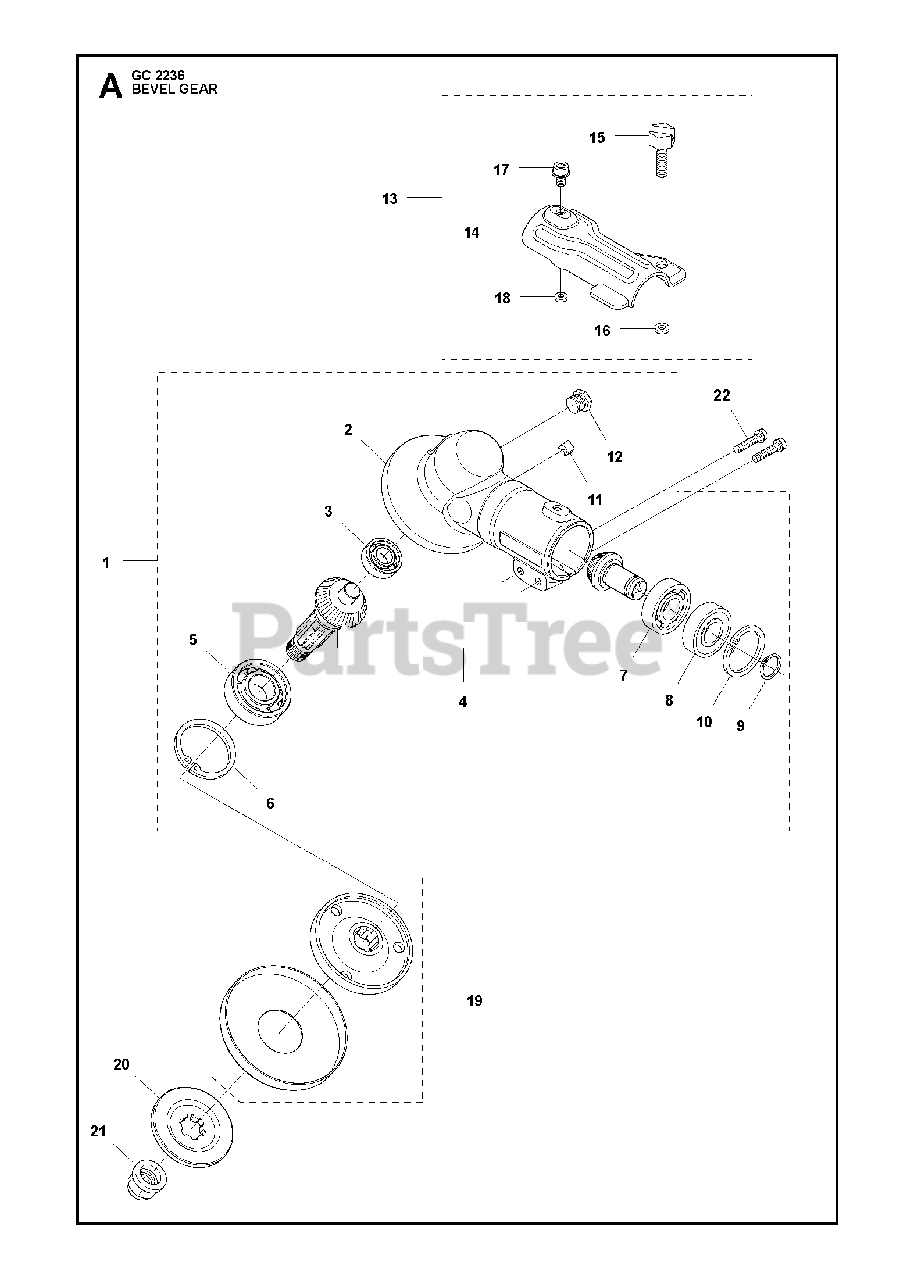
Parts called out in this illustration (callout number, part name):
1	%GEAR CASE ASSY
2	GEAR CASE
3	BALL BEARING 24X9X1/609ZR
4	SPARE PARTS KIT
5	BALL BEARING
6	RETAINING RING
7	BALL BEARING
8	BALL BEARING
9	SEEGER CLIP
10	RETAINING RING SGH 28
11	MAGNET
12	PLUG
13	CLAMP
14	RP HOLDER
15	SCREW
16	LOCKNUT M6
17	SCREW
18	LOCKING NUT
19	RP CARRIER
20	RP FLANGE
21	NUT BLADE
